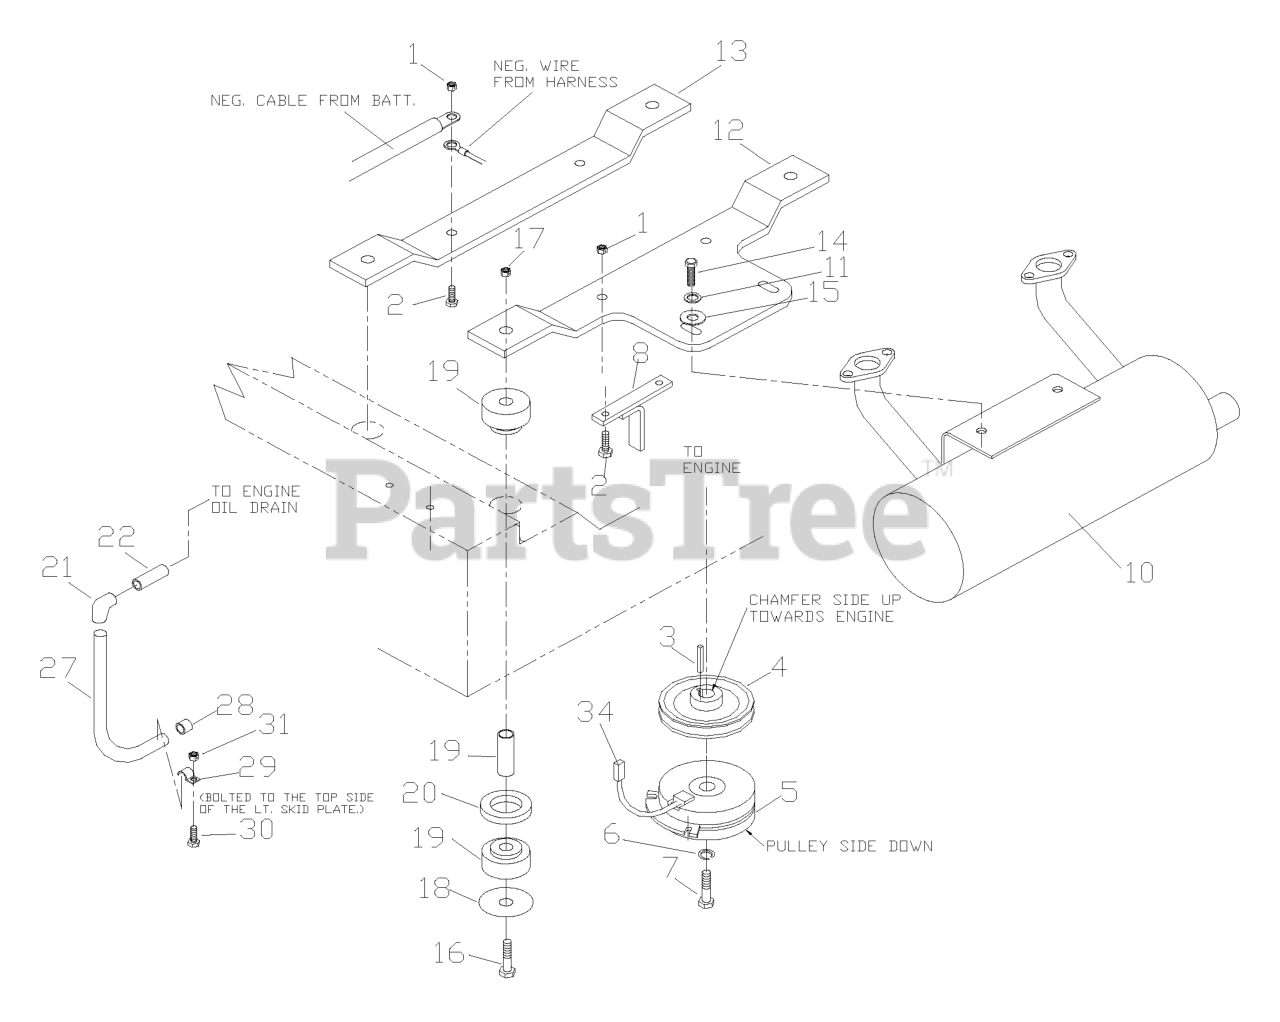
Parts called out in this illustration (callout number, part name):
1	NUT 5/16 LOCK
2	HCS 5/16 X 1.75
3	KEY 1/4 SQ.
6	WASHER 7/16 LOCK
7	HCS 7/16F X 2.5
8	CLUTCH TIE DOWN
11	WASHER 5/16 LOCK
12	ENGINE MOUNT
13	ENGINE MOUNT
14	HCS 5/16 X .750
15	WASHER 5/16 FLAT
16	HCS 1/2 X 3.25
17	NUT 1/2 NYLOC
22	3/8 NPT PIPE
27	OIL DRAIN HOSE
30	HCS 1/4 X .750
31	NUT 1/4 CTR. LOCK
34	CLUTCH PIGTAIL
